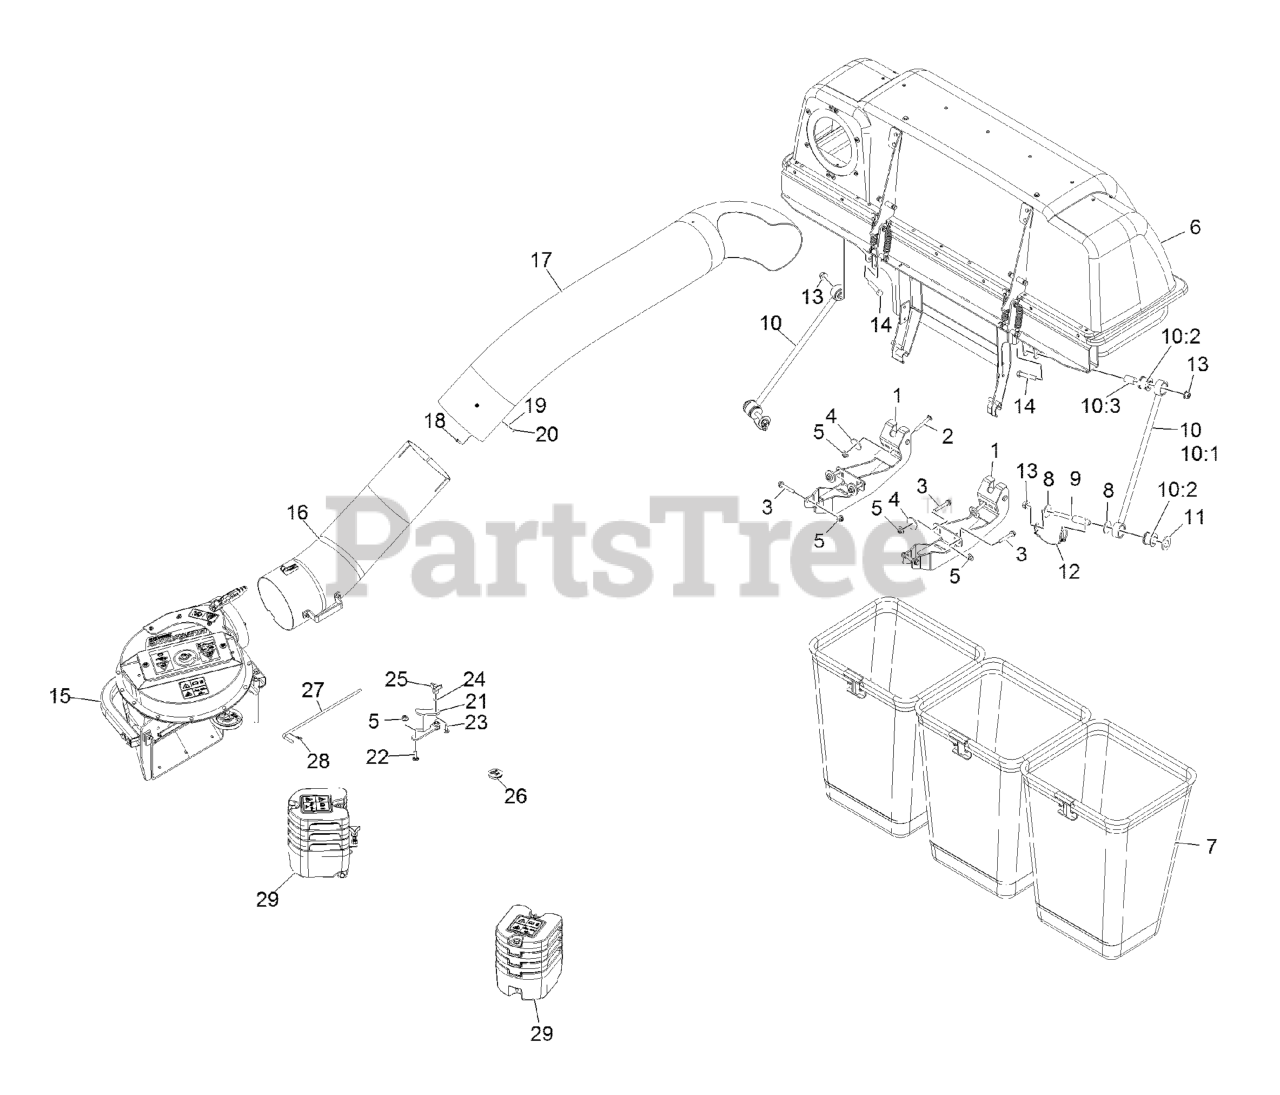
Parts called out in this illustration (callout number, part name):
1	MOUNT-BAGGER, LOWER
2	SCREW-CARR
3	Screw-HHF
4	Washer-Plain
5	Nut-Nyloc 3/8-16 Flg
7	BAG AND FRAME ASM
8	WASHER-THRUST
9	PIN-BAGGER BRKT
10	SUPPORT ROD ASM
10:1	Wld,Panhard Rod
10:2	BUSHING-RUBBER
11	Washer-Flat
12	PIN-MOUNT, BAGGER
13	Nut-Lock 1/2-13
14	SCREW-HH
15	ASM, BLOWER LARGE - SVC O
16	LOWER TUBE ASM
17	TUBE-UPPER
18	SCREW-HWH
19	WASHER-FLAT
20	NUT-LOCK, NI
21	BRACKET,BELT COVER
22	Bolt-Carriage 3/8-16 X 1 1/4
23	BOLT-CARR
24	RING-RETAINING, BOLT
25	KNOB-3 PRONG
26	PLUG, BLACK NYLON 1.75
27	PIN,CHUTE PIVOT
28	PIN-COTTER
29	ASM-Caster Weight
